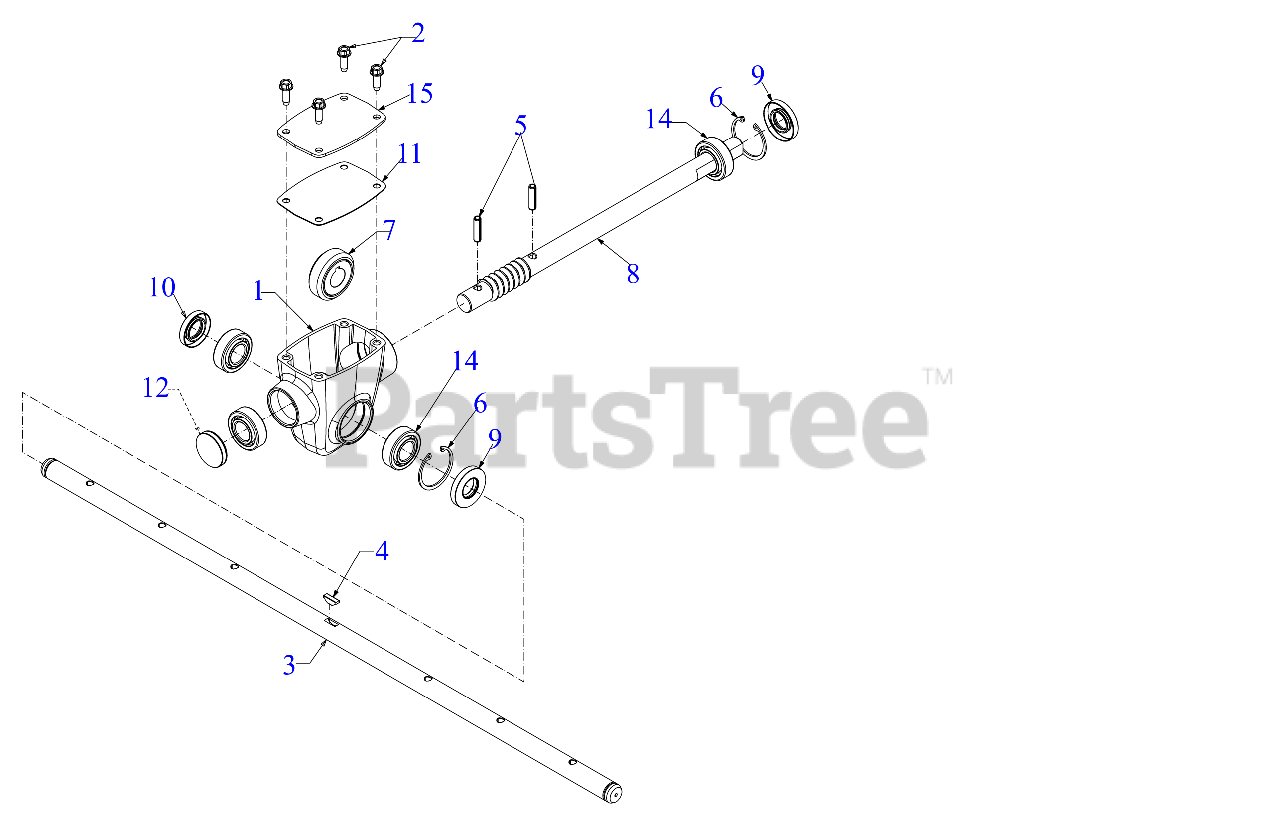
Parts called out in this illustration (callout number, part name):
1	AUGER HOUSING GEARBOX
2	SCREW 1/4-20 x .750
3	30" AUGER AXLE
4	KEY 3/16 x 5/8 HI-PRO
7	WORM GEAR 20T
8	WORM SHAFT
11	GEARBOX COVER GASKET
12	GEARBOX PLUG
14	BALL BEARING
15	GEARBOX COVER
